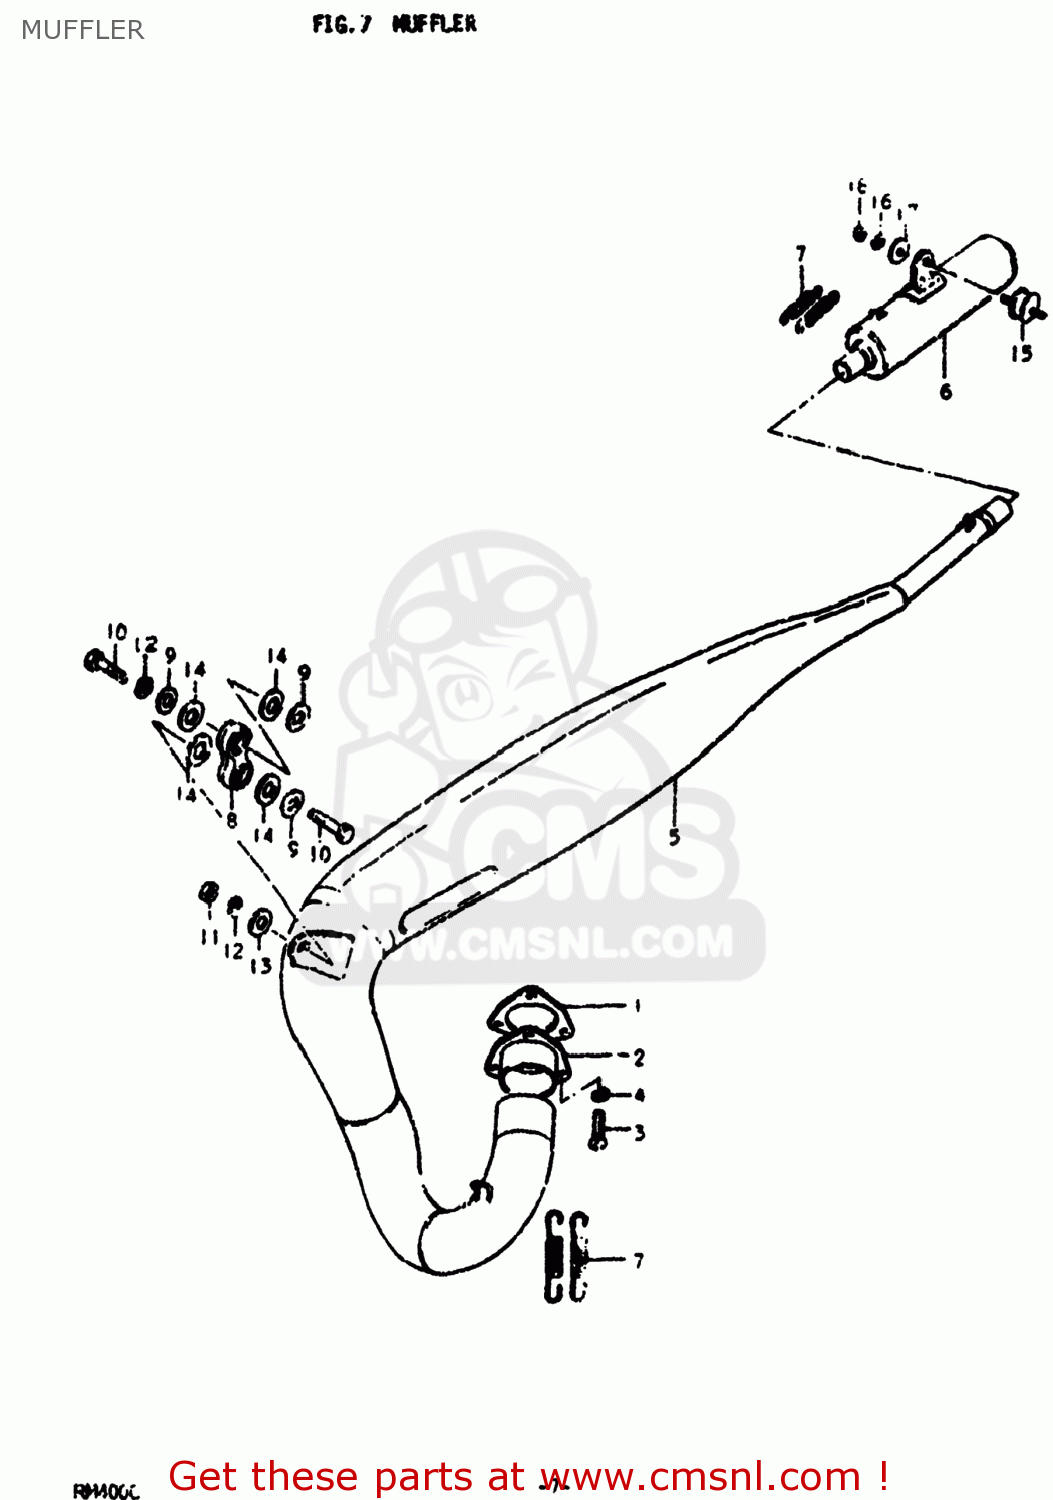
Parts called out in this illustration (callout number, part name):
1	GASKET,EXHAUST PIPE (MCA)
2	FLANGE,EXHAUST PIPE
3	SCREW
4	LOCK WASHER
5	BODY,MUFFLER
6	BODY,MUFFLER
7	SPRING
8	DAMPER, MUFFLER
9	WASHER
10	BOLT
11	NUT
12	LOCK WASHER
13	WASHER
14	WASHER(13X28X1.6)
15	DAMPER,MUFFLER SUPPORT
16	LOCK WASHER
17	WASHER (8.2X20X1.6)
18	NUT
